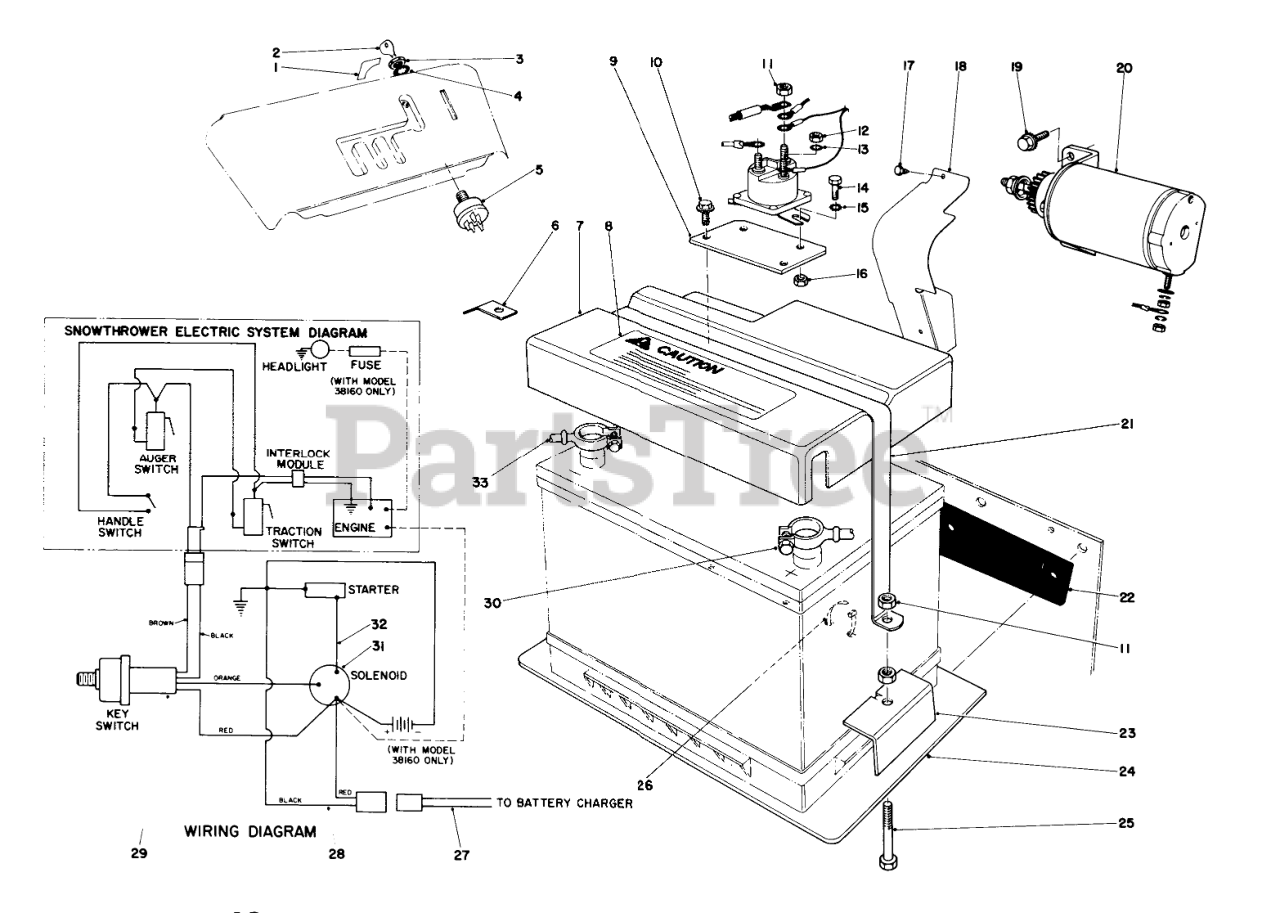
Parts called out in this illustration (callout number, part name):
1	Decal Switch
2	Key
3	NUT-HH
4	WASHER-TOOTH, INTERNAL
5	Smarter Switch
6	Bracken Wire Clamp
7	Battery Cover (Incl. Ref. #8)
8	Decal-Caution
9	Bracket Solenoid
10	SCREW-HWH
11	NUT-HEX
12	NUT-HEX
13	WASHER-LOCK, INT
14	SCREW-HH
15	WASHER-LOCK/EXT
16	NUT-LOCK, NI
17	Hex Hd. Sems Screw
18	Pinion Shield
19	Screw-HH
20	Starter Motor & Pinion Assy.
21	Strap Battery
22	Batery Isolation Pad
23	BATTERY CLAMP
24	Battery Mounting Plate
25	SCREW-HH
26	TIE-CABLE
27	MALE WIRE ASM
28	FEMALE WIRE ASM
29	Wire Harness
30	BATT-SOLENOID CABLE
31	SOLENOID
32	STRT MTR-SOLNOID WIRE
33	BATT-GROUND CABLE
